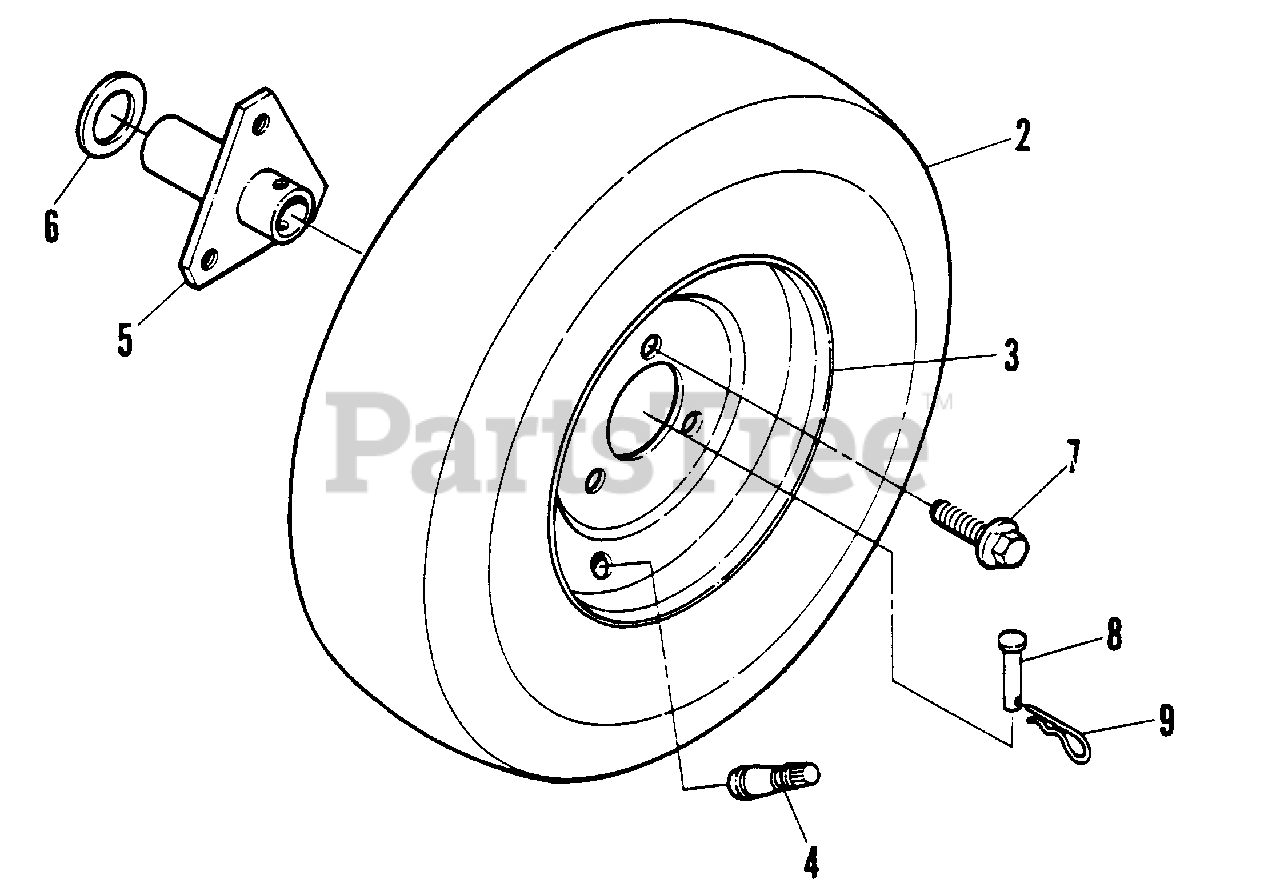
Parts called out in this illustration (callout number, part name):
2	TIRE, 16 x 4.80 - 8
3	RIM,
4	VALVE, Snap-In
5	HUB, Wheel
6	WASHER, 3/4 x 1-1/8" Thrust
7	BOLT, 1/2-20 x 3/4" Hex Head Lug
8	PIN, 5/16 x 1-11/16 Clevis
9	PIN, 3/32 x 1-1/2" Hair
